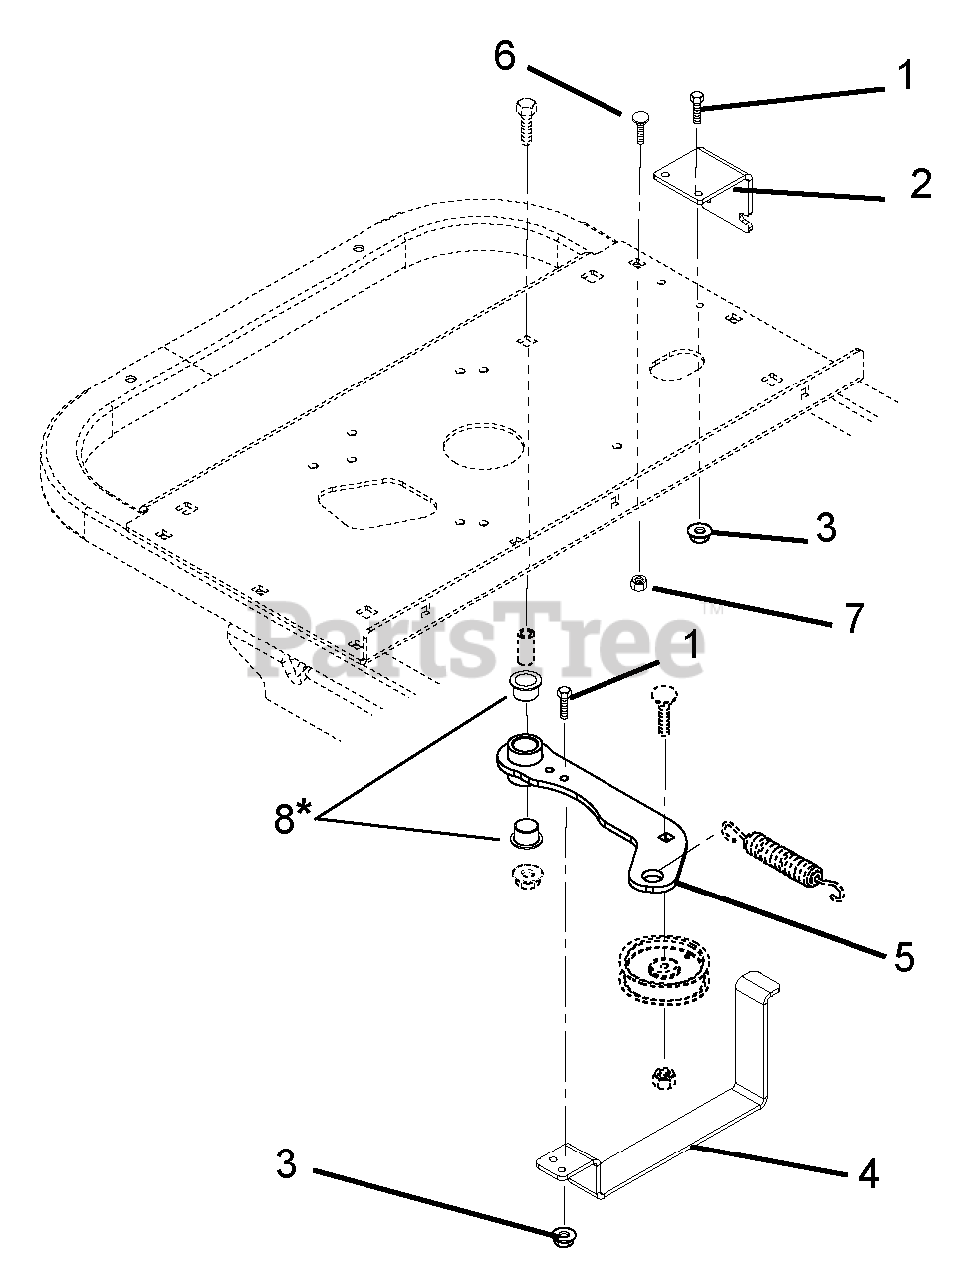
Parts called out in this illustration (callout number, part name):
1	@BLT-HEX .25-20X.75 GR5 YWZC
2	LATCH,COLD START
3	@NUT-LK-TOP-FLG .25-20 YWZC
4	HANDLE,COLD START
5	WMT, IDLER ARM
6	@BLT-RDHDSQNK .38-16X2.00 G2YZ
7	@NUT-LK-CTR-JAM .375-16 YWZC
8	BSHG-FLG 0.75X0.875X.625X1.125
